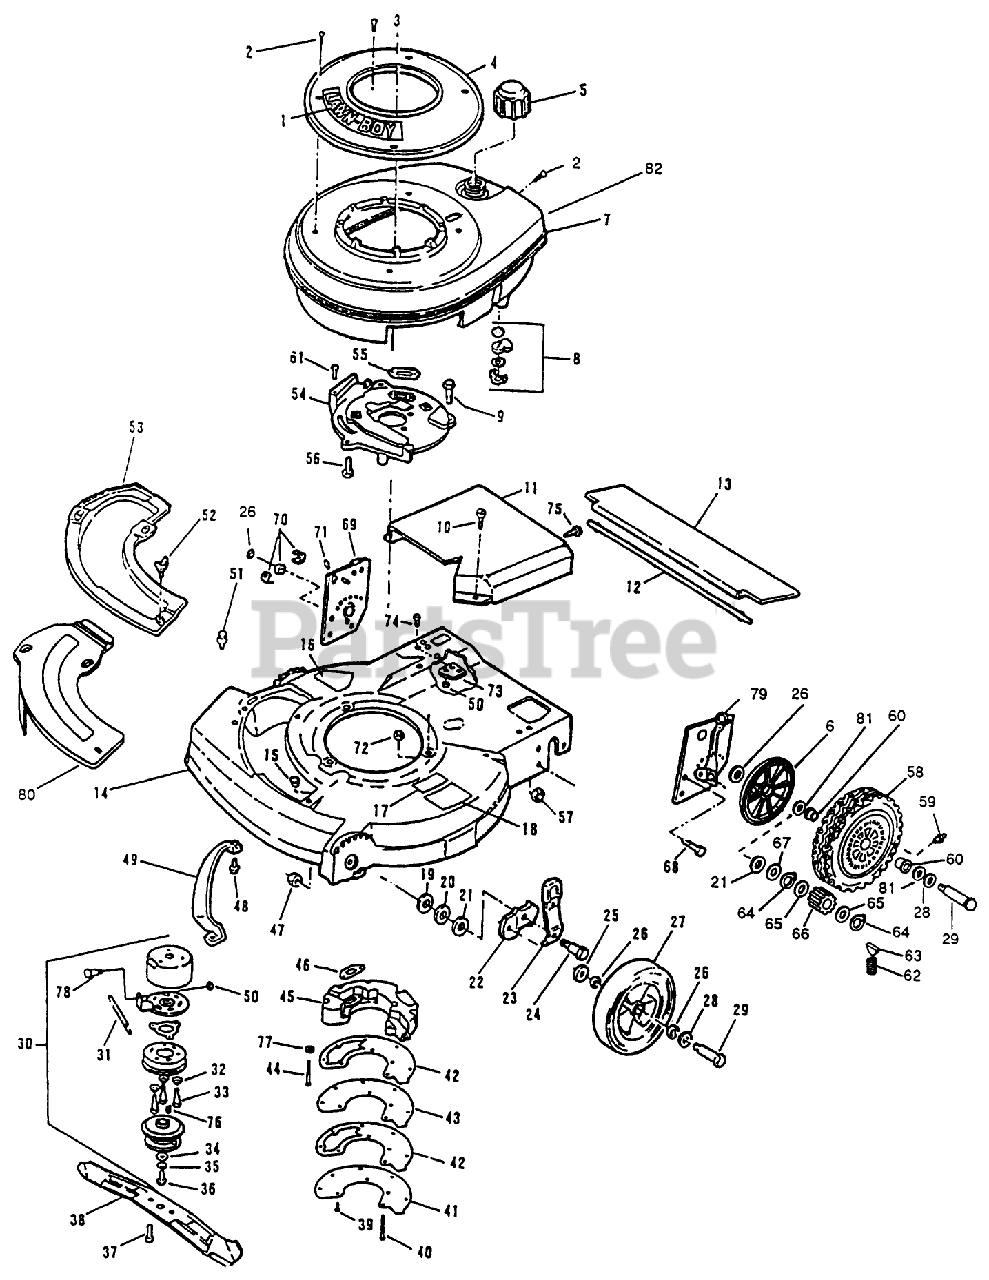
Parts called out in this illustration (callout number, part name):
2	SCREW - SELF TAPPING
3	SCREW SEMS SM
4	STARTER BASE&NUT*B
5	FUEL CAP & INSERT
7	SHROUD,TANK&VAL
8	SHUT OFF VALVE KIT
9	SCREW-HH
10	SCREW SEMS TRM HEX HD
13	SHIELD-TRAILING
14	HOUSING ASM
18	PAD FOOT
19	WASHER
20	WASHER
21	WASHER
23	SPRING ARM ASM
24	BOLT
25	WASHER WROUGHT
26	WASHER
28	SPACER
29	BOLT WHEEL
31	SPRING
33	SCREW,SHOULDER SM
34	WASHER
37	SCREW SEMS
38	21" Blade
39	SCREW
42	GASKET F
47	LOCKNUT
49	BAR-TOE
50	LOCKNUT E
52	WING SCREW LAWRE
56	SCREW V
57	NUT-LOCK F
59	FITTING LINCOLN
61	SCREW-HH
62	SPRING
63	KEY
64	RET RING
65	SPACER/GR ALGHNY
66	PINION BROCKWAY
67	THRUST WASHER
69	HEIGHT ADJ AY-RH
70	REAR AXLE BEARING
71	**FITTING LINCOLN
72	NUT-LOCK F
73	BOLSTER
76	KEY
81	WASHER-FELT
